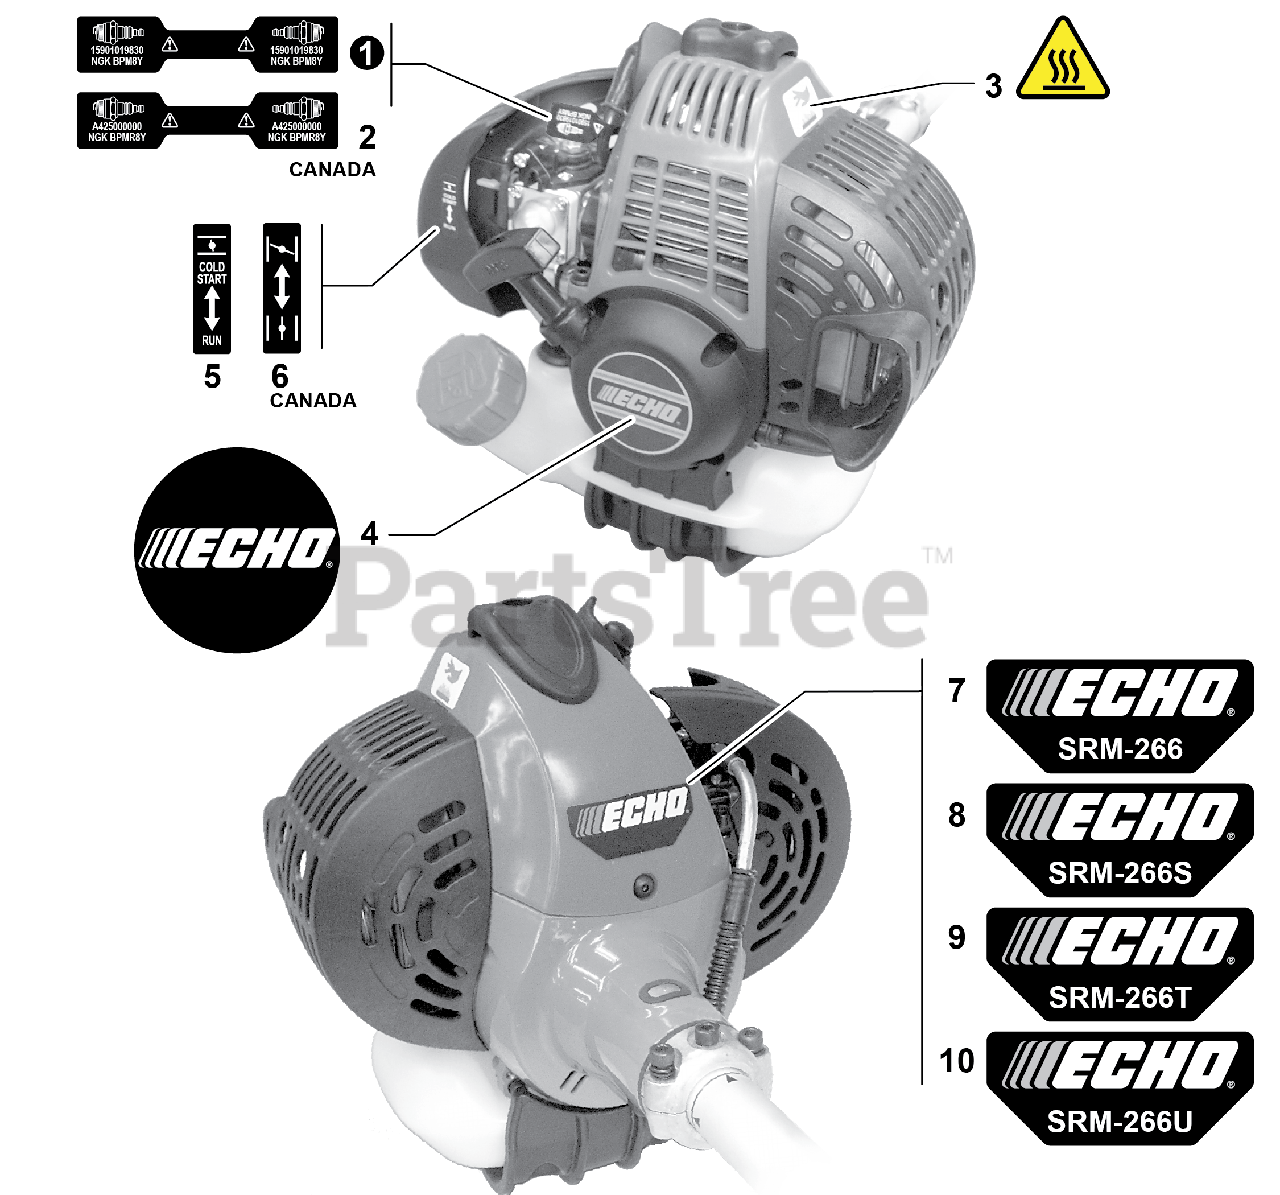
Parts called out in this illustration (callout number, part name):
1	LABEL, SPARK PLUG - BPM8Y
2	LABEL, SPARK PLUG - BPMR8Y
3	LABEL, CAUTION - HOT
4	LABEL, ECHO
5	LABEL, CHOKE
6	LABEL, CHOKE
7	LABEL - MODEL SRM-266
8	LABEL - MODEL SRM-266S
9	LABEL - MODEL SRM-266T
10	LABEL - MODEL SRM-266U
